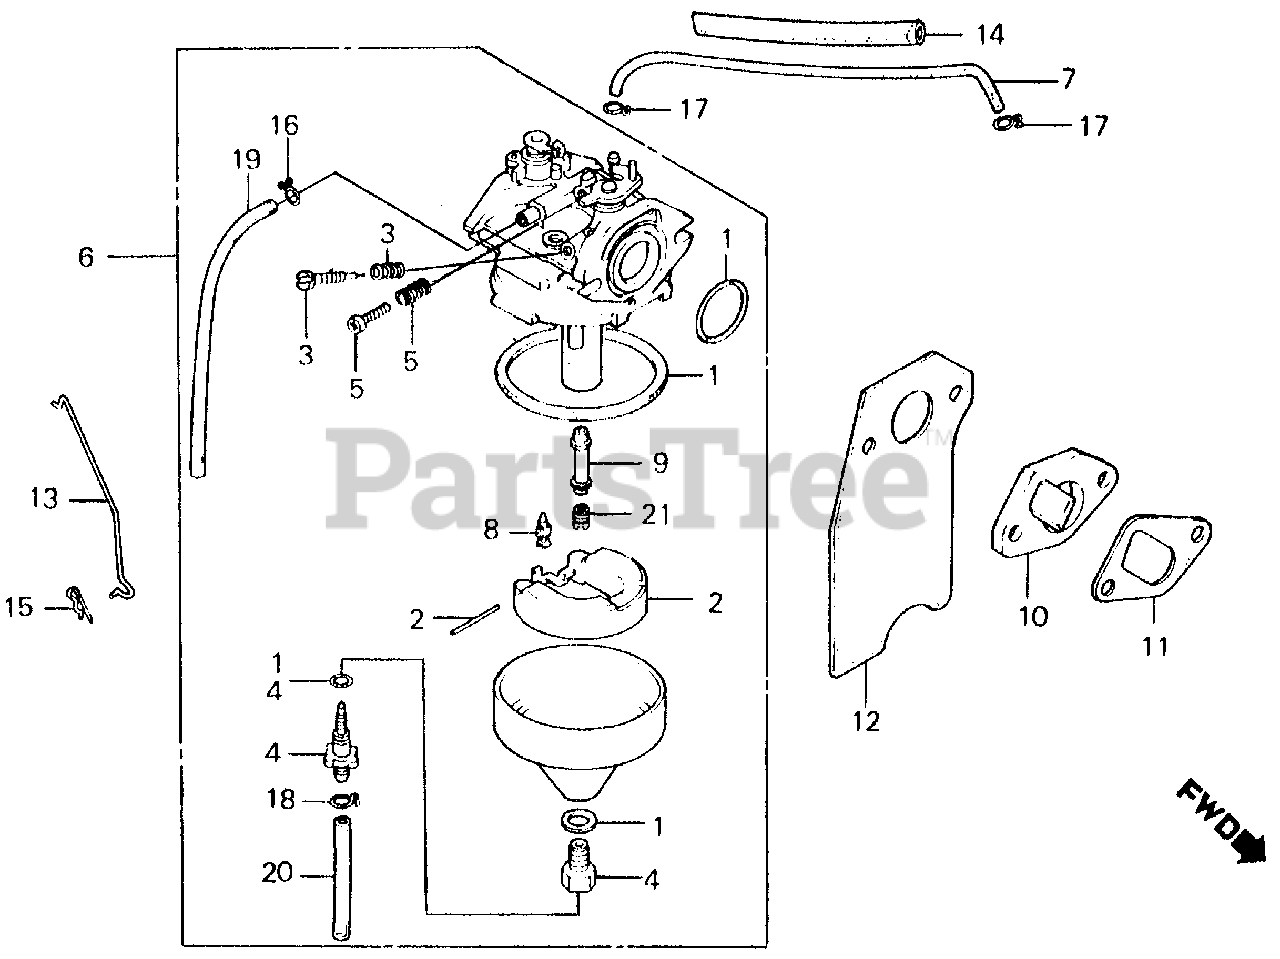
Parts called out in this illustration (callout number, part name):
1	GASKET SET
3	SCREW SET A
4	SCREW SET, DRAIN (NOT AVAILABLE)
5	SCREW SET B (NOT AVAILABLE)
6	CARBURETOR ASSY.
7	TUBE, FUEL (NOT AVAILABLE)
8	VALVE, FLOAT
9	NOZZLE, MAIN (NOT AVAILABLE)
10	INSULATOR, CARBURETOR (NOT AVAILABLE)
11	GASKET, INSULATOR
12	GASKET, CARBURETOR
13	ROD, CHOKE (NOT AVAILABLE)
13	ROD, CHOKE
14	RUBBER, SUPPORTER
15	PIN, LOCK (NOT AVAILABLE)
15	PIN, LOCK (4MM)
16	CLIP, TUBE (B7)
17	CLIP, TUBE (B8)
18	CLIP, TUBE (B6.5)
19	BULK HOSE, VINYL (3.5X6.5X8000) (3.5X6.5X150)
20	BULK HOSE, VINYL (4X7X8000) (4X7X50)
21	JET, MAIN (#52)
21	JET, MAIN (#45)
21	JET, MAIN (#48)
21	JET, MAIN (#50)
